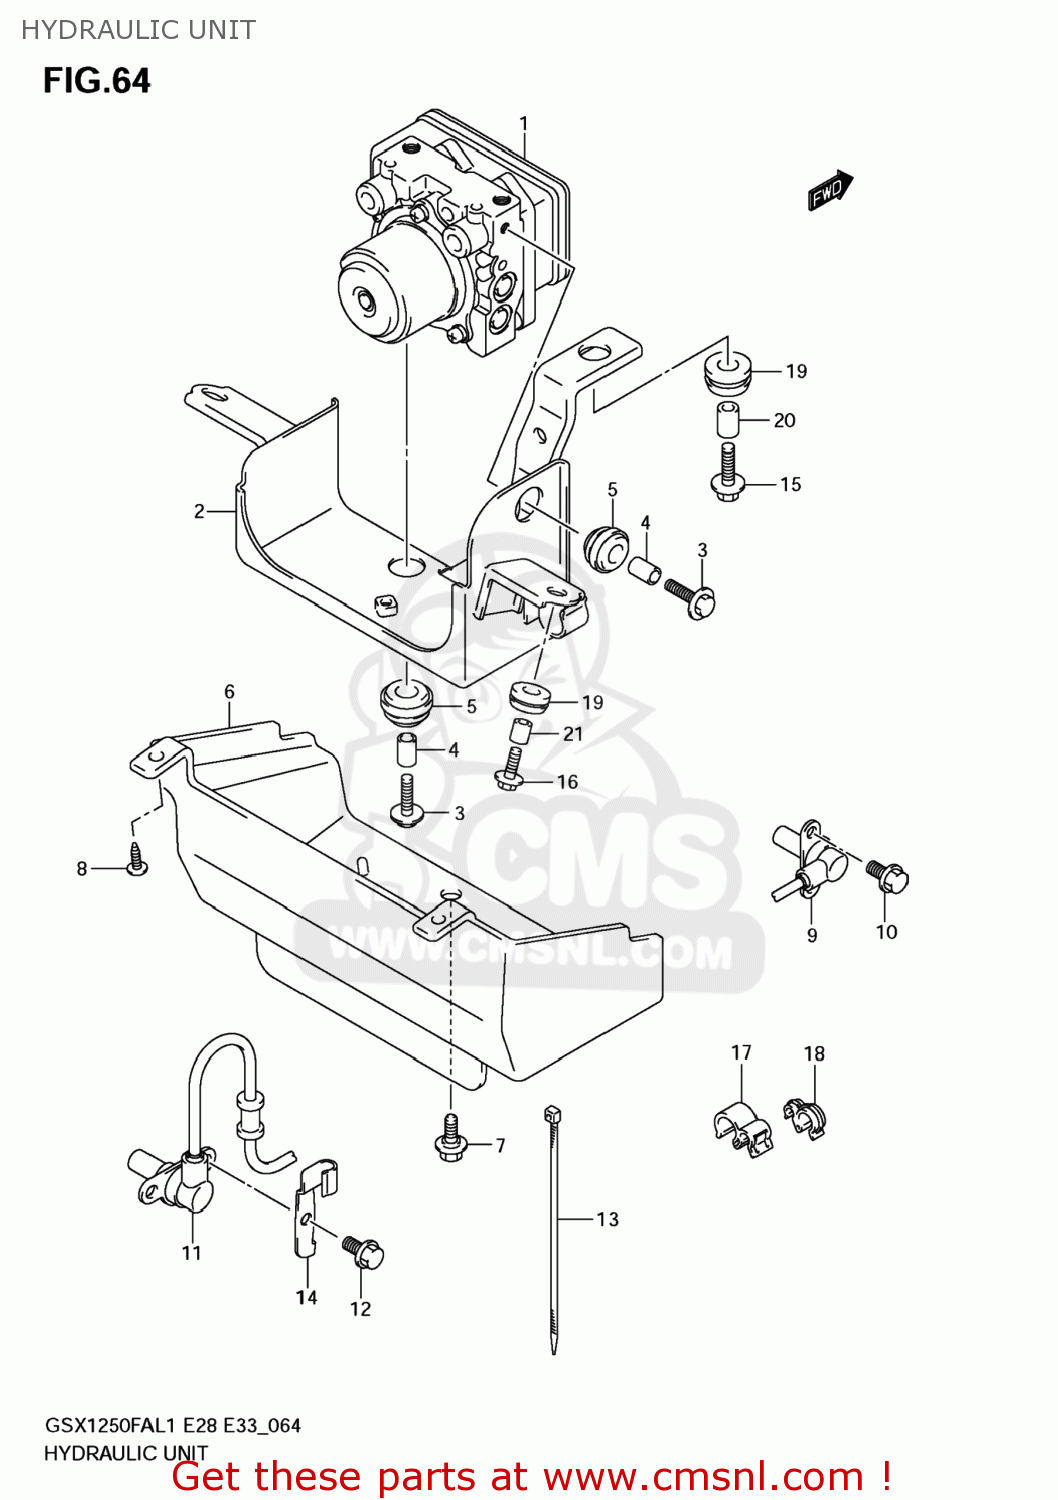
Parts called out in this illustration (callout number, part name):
1	UNIT ASSY,HYDRAULIC
2	HOLDER,HYDRAULIC UNIT ABS
3	BOLT,HYDR UNIT MTG
4	SPACER,HYDR UNIT MTG
5	RUBBER,HYDR UNIT MTG
6	COVER,HYDR ABS UNIT
7	BOLT(6X16)
8	SCREW
9	SENSOR,FR WHEEL ABS
10	BOLT
11	SENSOR,RR WHEEL ABS
12	BOLT
13	CLAMP(L:145)
14	CLAMP,ABS SENSOR RR
15	BOLT(6X20)
16	BOLT(6X25)
17	CLAMP
18	CLAMP
19	CUSHION
20	SPACER(6.5X9X8)
21	SPACER(6.5X9X11.5)
